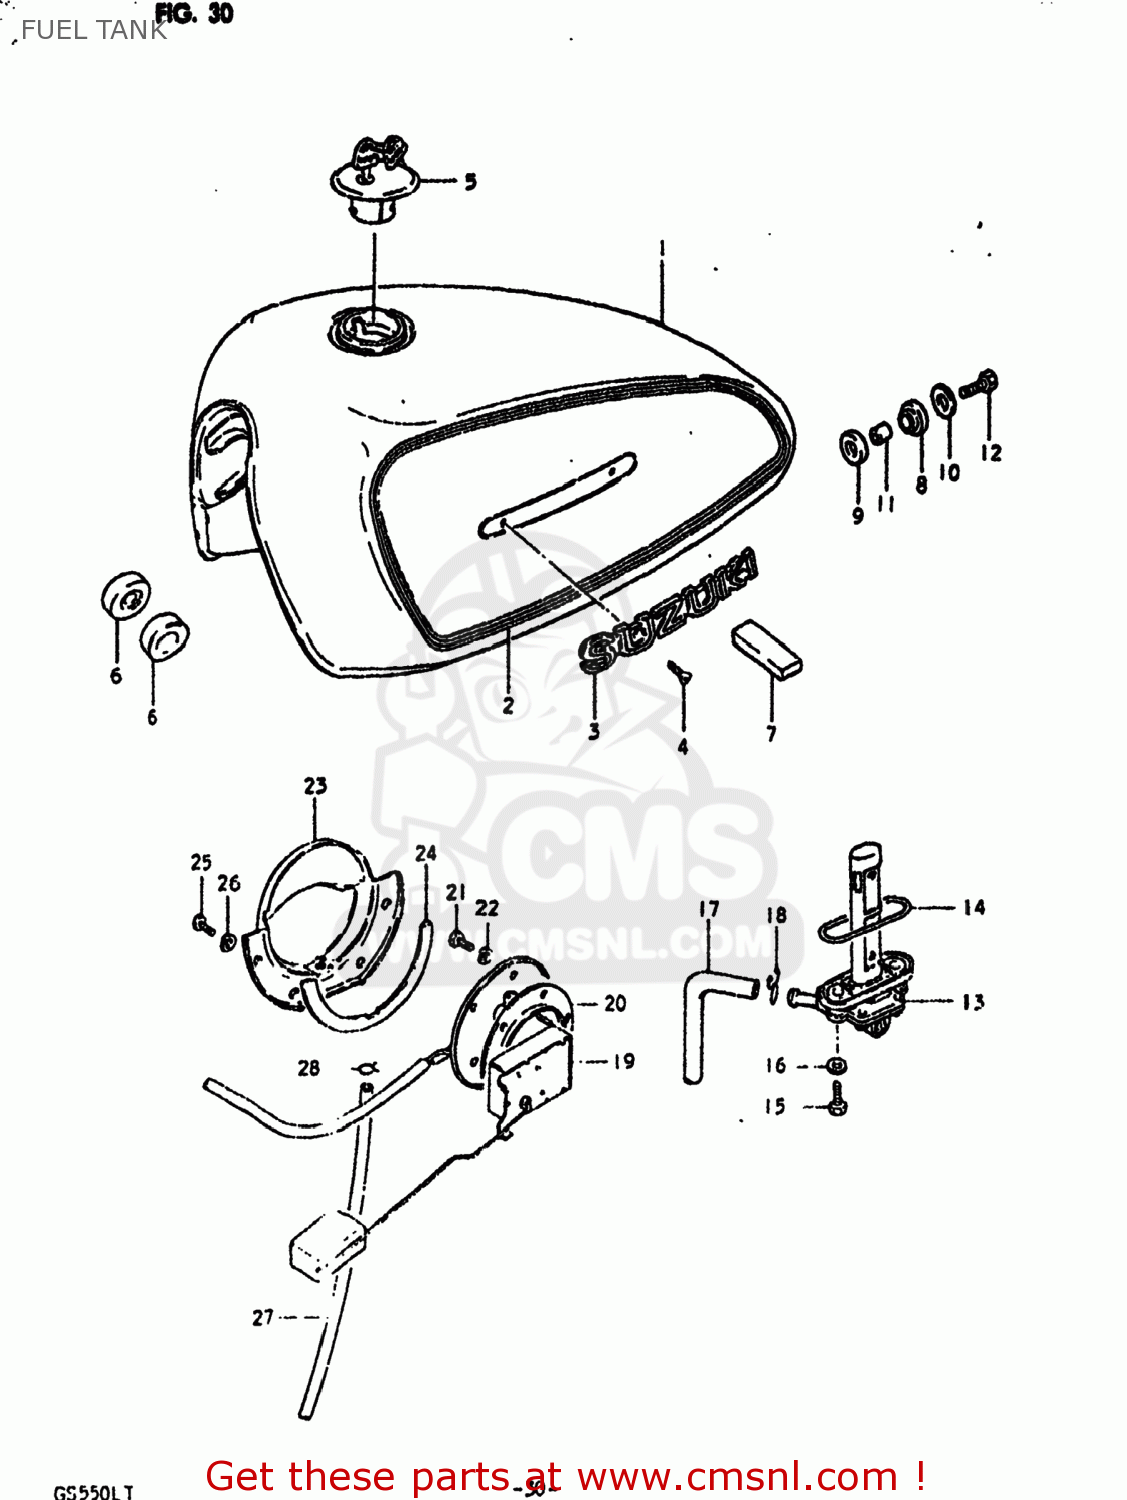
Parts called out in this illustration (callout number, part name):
1	TANK, FUEL
2	TAPE SET,FUEL TANK
3	EMBLEM
4	SCREW 3X6
5	CAP SET,FUEL TANK
6	CUSHION
7	CUSHION
8	CUSHION
9	CUSHION
10	WASHER (8.5X29X1.6)
11	SPACER(8.5X12X19)
12	BOLT (8X30)
13	COCK ASSY,FUEL
14	GASKET (NAS)
15	SCREW (6X25)
16	GASKET
17	HOSE
18	CLIP
19	GAUGE ASSEMBLY,FUEL LEVEL
20	GASKET,FUEL LEVEL GAUGE (NAS)
21	BOLT
22	LOCK WASHER
23	PLATE,FUEL DRAIN
24	GASKET,FUEL DRAIN PLATE (NAS)
25	SCREW
26	LOCK WASHER
27	HOSE,FUEL
28	CLIP
